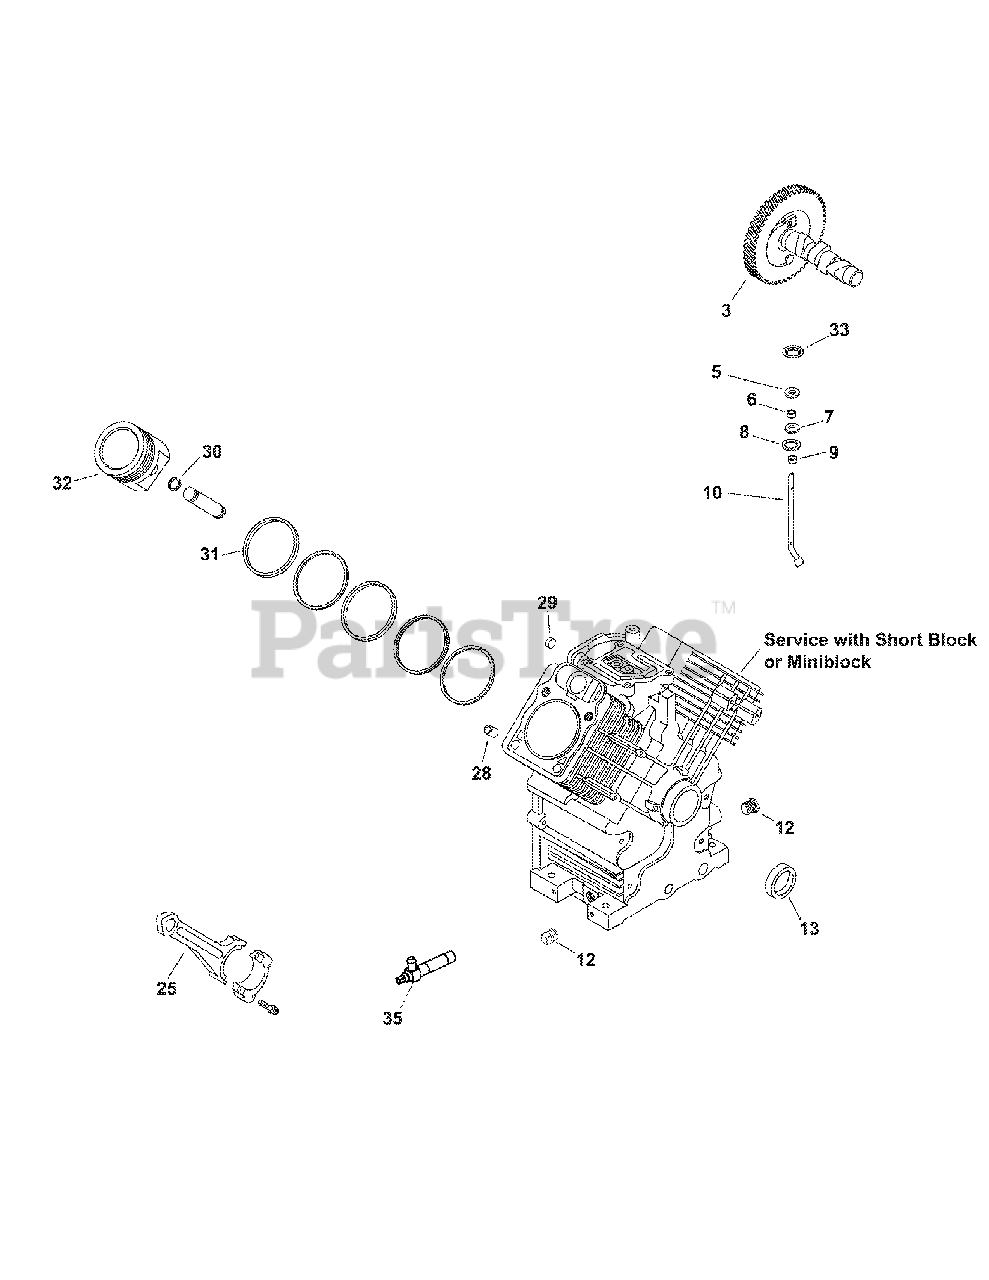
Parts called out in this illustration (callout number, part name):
3	Kit, Camshaft
5	Washer, Flat 9 MM
6	Rod Assy, Connecting
7	Seal, Governor Cross Shaft
8	Washer, Flat 11/32"
10	Shaft, Governor Cross
12	Plug, Sq Head Pipe 3/8"
25	Connecting Rod
28	Pin, Locating
30	Retainer, Piston Pin
31	Ring Set (STD)
31	Ring Set (.08)
31	Ring Set (.25)
31	Ring Set (.50)
32	Kit, Piston Assy w/Ring (STD)77MM
32	Kit, Piston Assy w/Ring Set (.08)77MM
32	Kit, Piston Assy w/Ring Set (.25)77MM
32	Kit, Piston Assy w/Ring Set (.5)77MM
33	Retainer, Ring
35	Valve, oil drain
